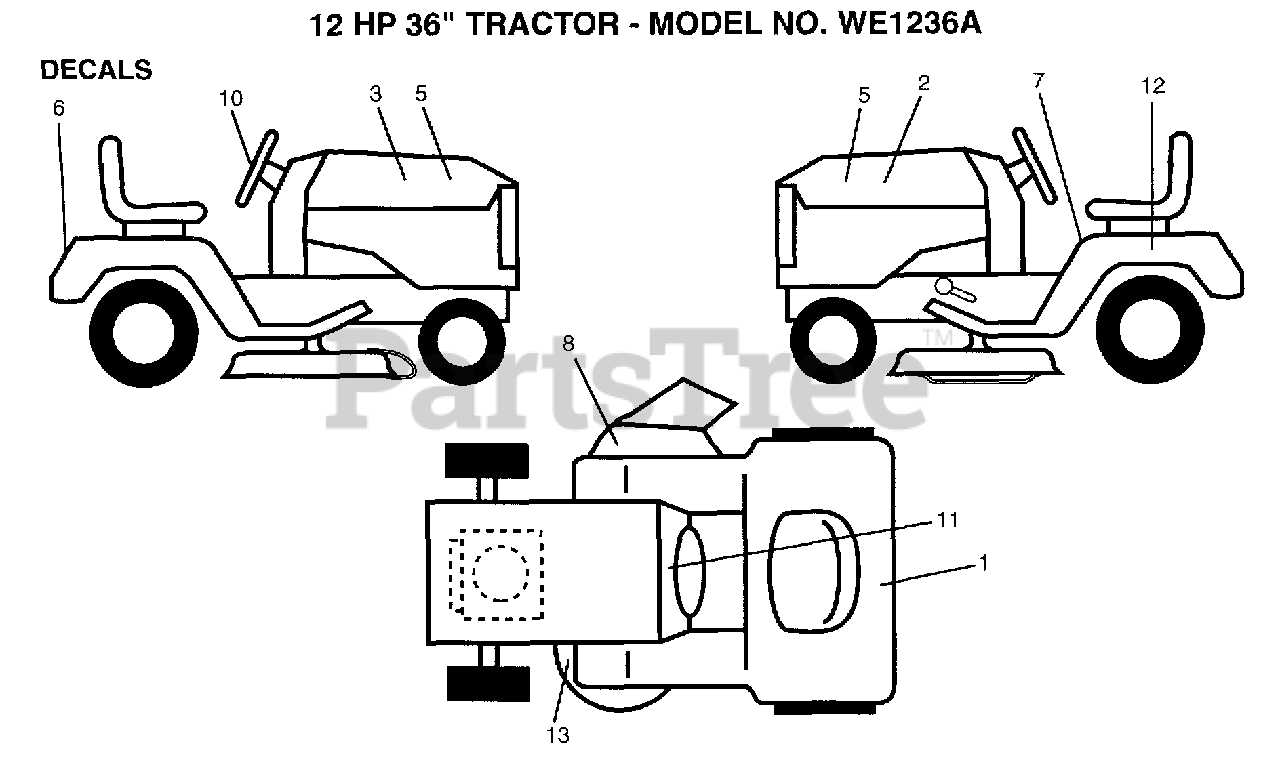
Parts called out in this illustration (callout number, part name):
1	DECAL
2	DECAL STRIP HD LH
3	DECAL STRIP HD RH
5	DECAL PNL SIDE RH
6	DECAL.FENDER
7	DECAL CAUT FEND
8	"DECAL, WARNING"
10	DECAL.WHL.STRG.
11	DECAL OP INST E/S
12	DECAL.FEND.QUICKS
13	DECAL.V.BELT
